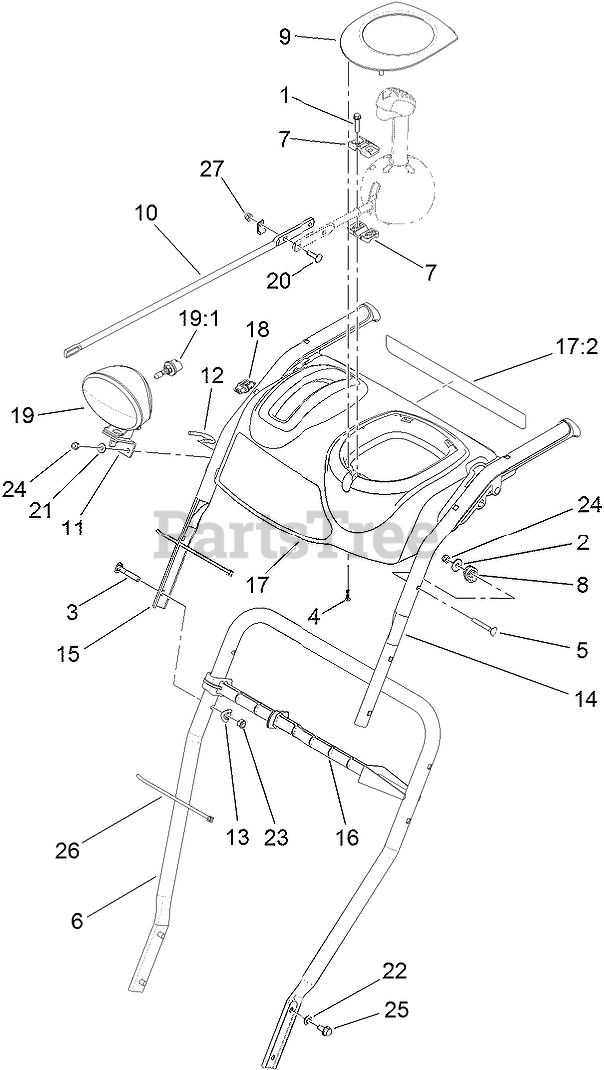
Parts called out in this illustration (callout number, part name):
1	SCREW-PLASTITE
2	WASHER-PLAIN
3	SCREW-HANDLE
4	SCREW-PPH
5	SCREW
6	HANDLE-LOWER
7	SUPPORT-ROD
8	CLAMP-CABLE
9	COVER-PANEL, CONTROL
10	ROD-CHUTE, FRONT
11	BRACKET-LIGHT
12	CLAMP
13	WASHER
14	HANDLE-UPPER, LH
15	HANDLE-UPPER, RH
16	STICK-CLEANOUT
17	PANEL-CONTROL
17:2	DECAL-WARNING
18	HARNESS-WIRE, HEADLIGHT
19	HEADLAMP ASM
19:1	LAMP-12 VOLT
20	SCREW-CARR
21	WASHER-FLAT
22	WASHER-BELLEVILLE
23	NUT-LOCK, NI
24	NUT-LOCK, NI
25	SCREW-HWHTF
26	TIE-CABLE
27	NUT-LOCK, NI
